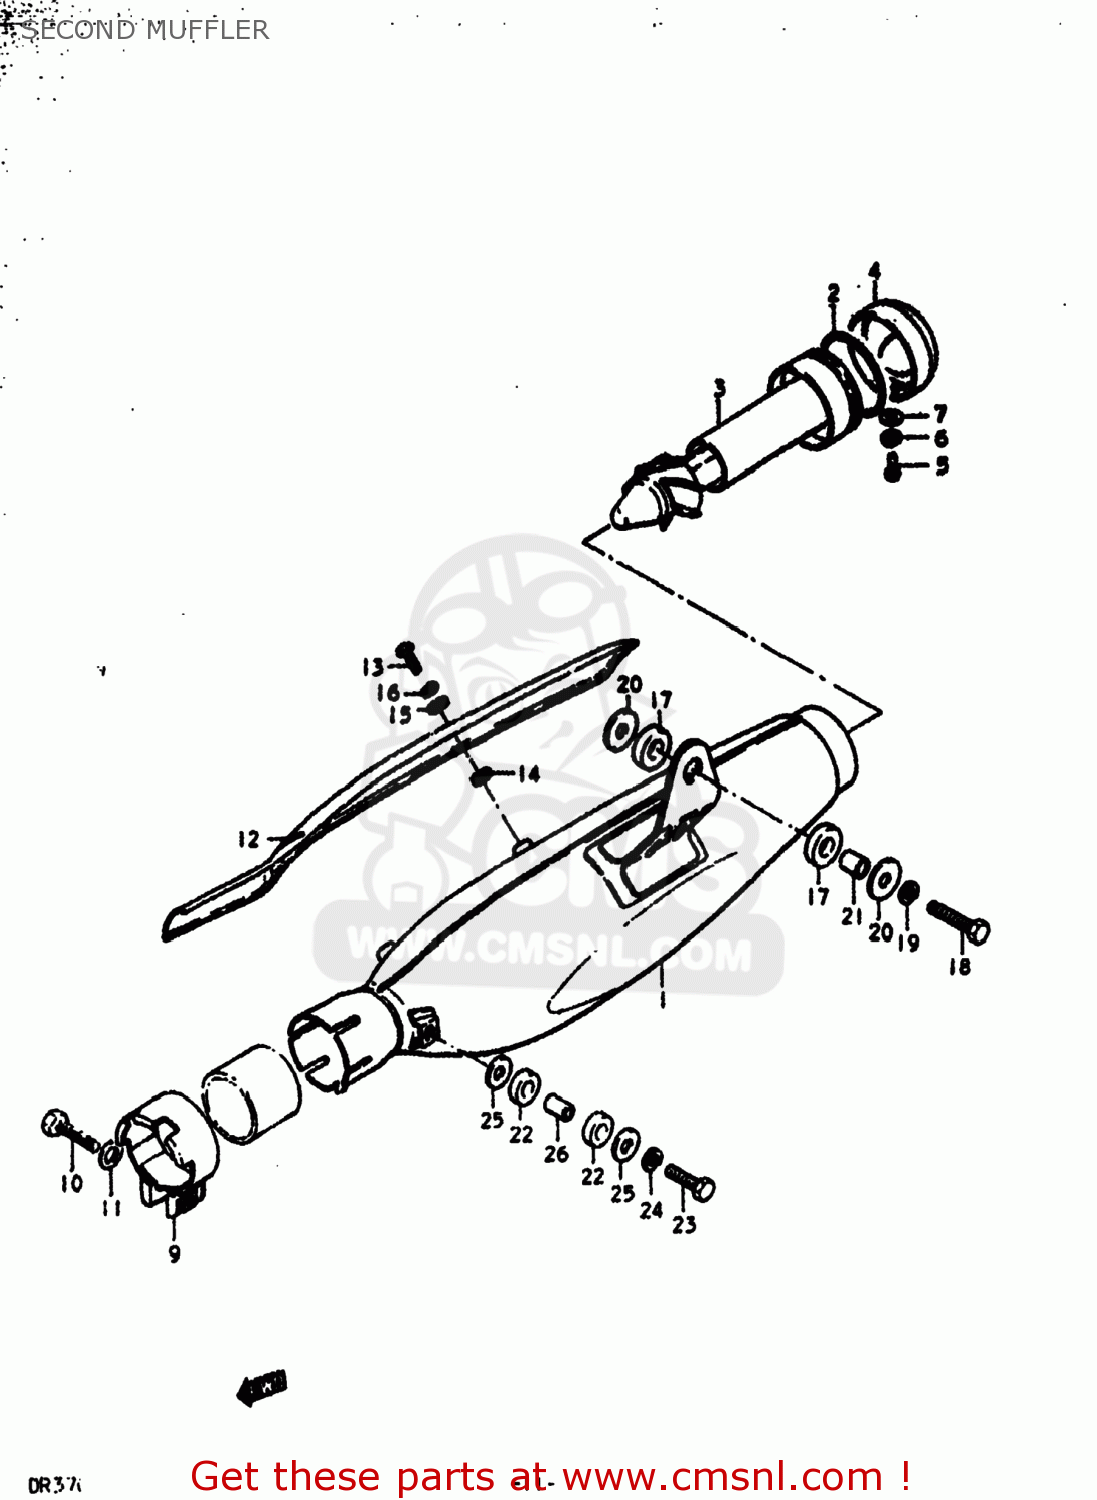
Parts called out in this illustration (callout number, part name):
1	MUFFLER ASSEMBLY
2	O-RING (D:3.5 ID:54.4)
3	TUBE,MUFFLER CLEAN OUT
4	COVER,SECOND MUFFLER TAIL
5	SCREW(6X8)
6	LOCK WASHER
7	WASHER
8	CONNECTOR,MUFFLER
9	CLAMP
10	BOLT 8X35
11	WASHER
12	COVER,SECOND MUFFLER
13	SCREW 6X12
14	GASKET 6.2X12X1.5 (MCA)
15	WASHER
16	LOCK WASHER
17	CUSHION
18	BOLT (8X30)
19	LOCK WASHER
20	WASHER (8.5X29X1.6)
21	SPACER (8.6X13.8X8)
22	CUSHION
23	BOLT
24	LOCK WASHER
25	WASHER
26	SPACER (8.6X13.8X8)
